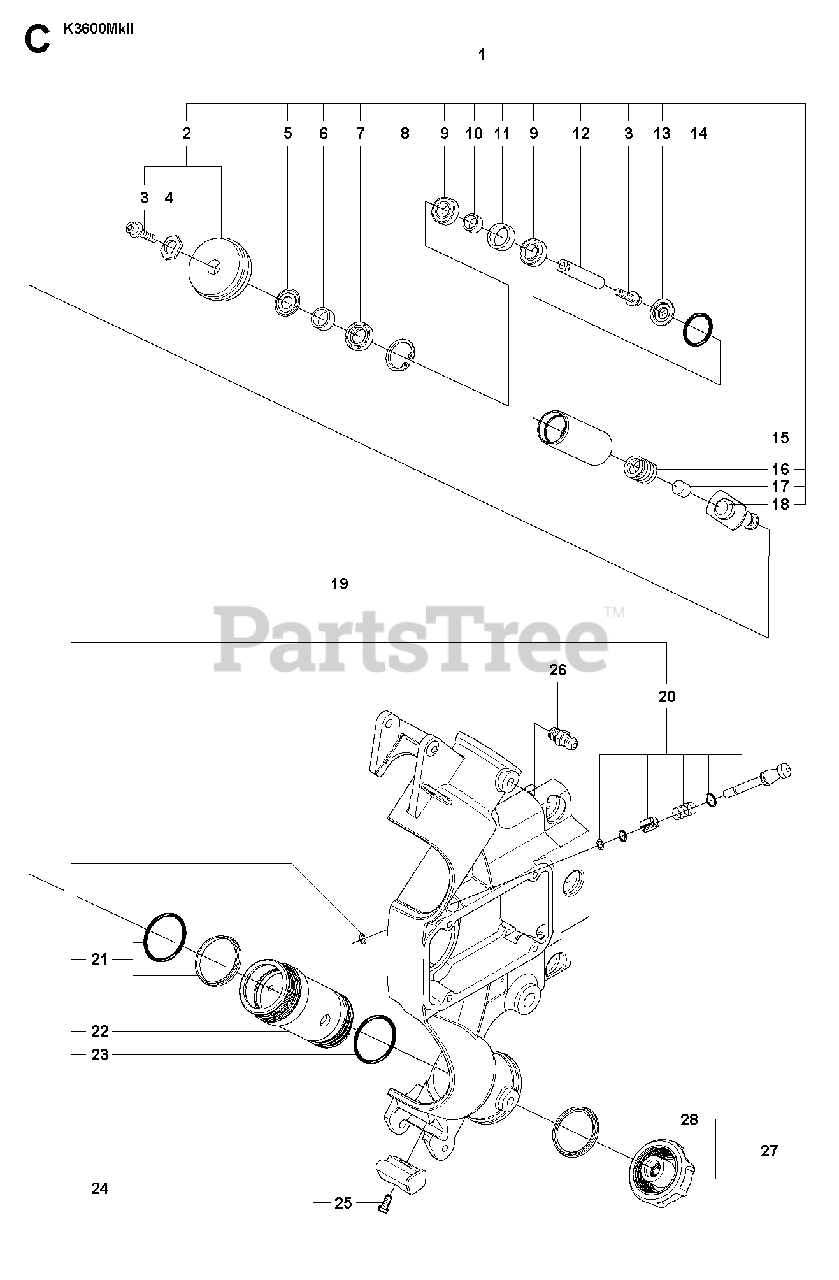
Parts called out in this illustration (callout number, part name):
1	BEARINGIncl. 2, 3, 5 - 18
1	BEARING CAGEIncl. 2, 3, 5 - 18. Sweden
2	GUIDE ROLLERIncl. 3, 4
2	GUIDE ROLLERIncl. 3, 4. Sweden only
9	BALL BEARING
19	CHASSISIncl. 2, 21, 22, 23, 24
24	WEAR PROTECTIONIncl. 25
26	LUBRICATION NIPPLE
